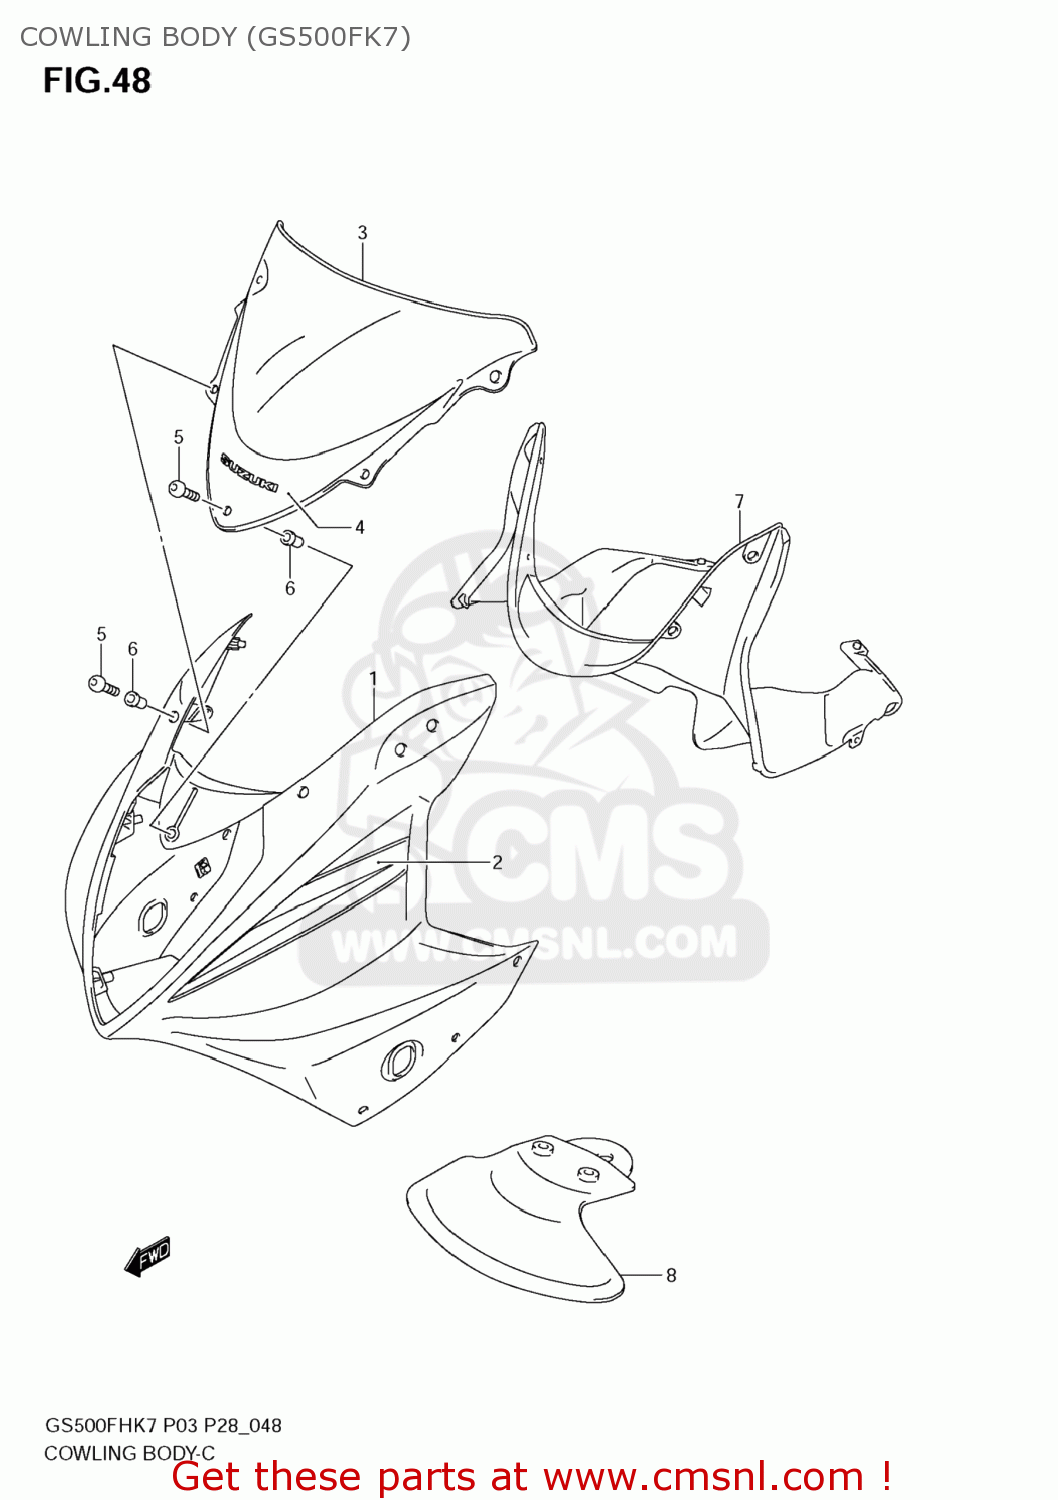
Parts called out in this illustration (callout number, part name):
1	BODY,COWLING G
2	TAPE SET,SIDE
3	WINDSCREEN
4	TAPE,WINDSCREEN
5	SCREW(5X18)
6	NUT
7	PANEL GS500F
8	COVER,LOWER BRA
